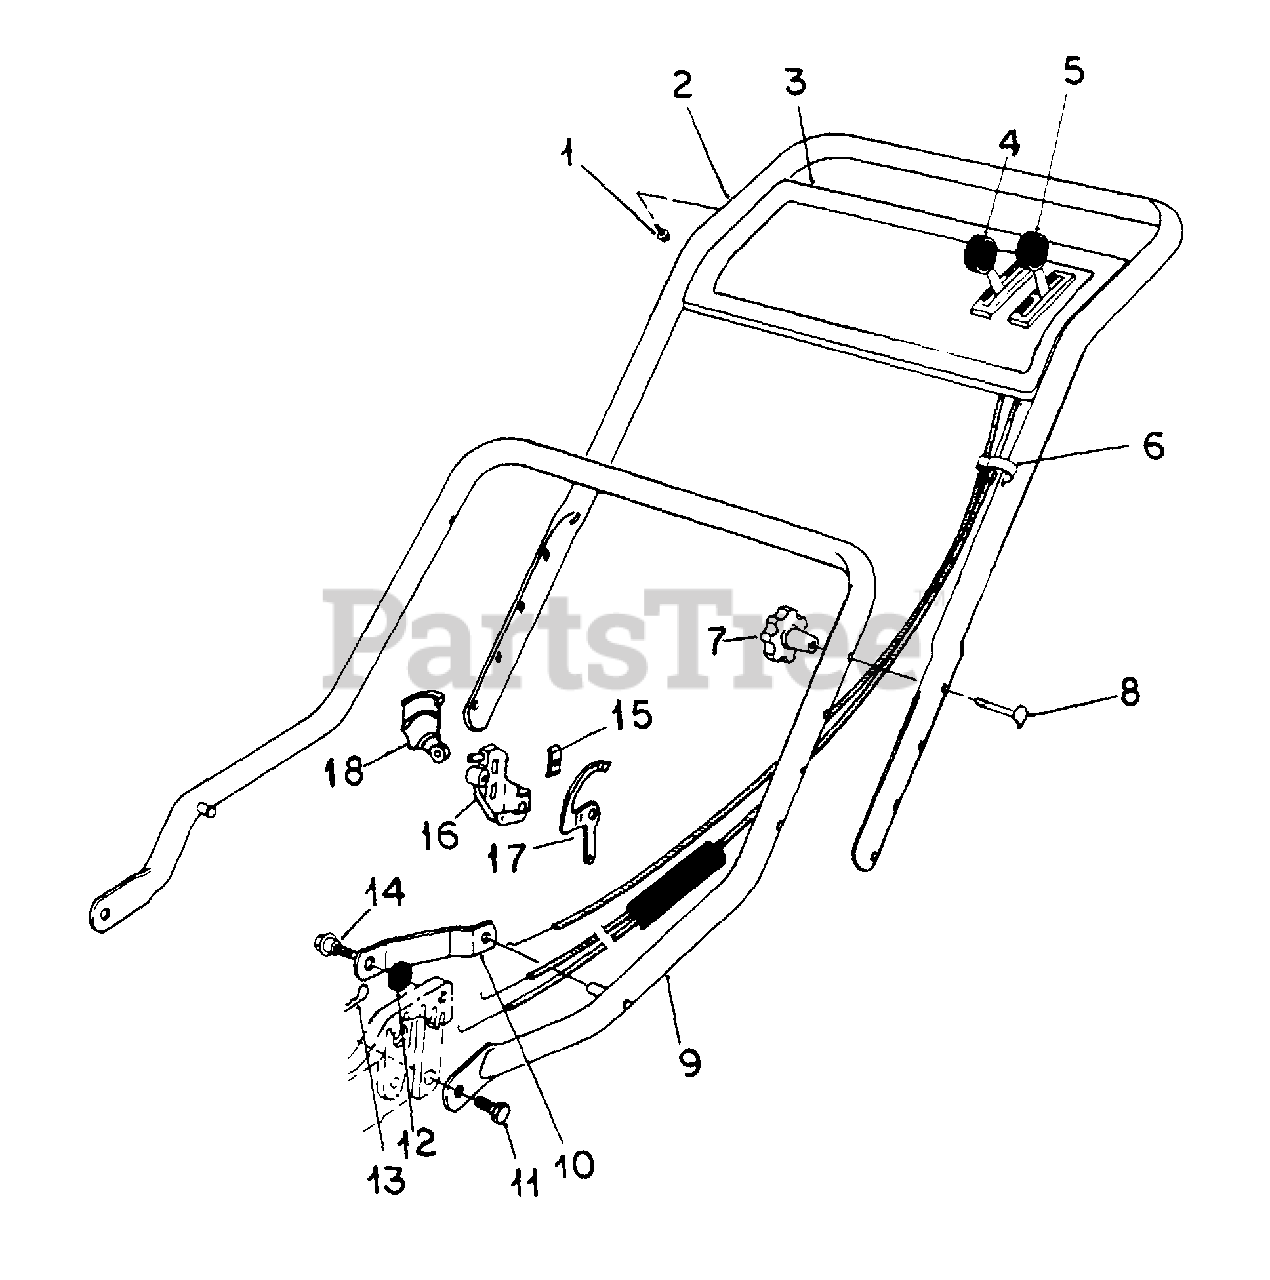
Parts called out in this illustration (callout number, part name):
2	HANDLE, UPPER
3	PLATE, CONTROL
4	CONTROL, THROTTLE
5	CONTROL, TRACTION
6	CLIP, CONDUIT
7	KNOB, HANDLE RELEASE
8	BOLT, HANDLE
9	HANDLE, LOWER
10	LATCH, HANDLE
11	BOLT, 5/16-18 X 1 ZND HEX-HD
12	SPACER, LATCH
13	PIN, HAIR PIN COT
14	BOLT, SHOULDER
14	SCREW, SHOULDER
15	CLAMP, CASING
16	BLOCK, CLAMP AND PIVOT
17	CAM, INTERLOCK
18	LEVER, INTERLOCK
